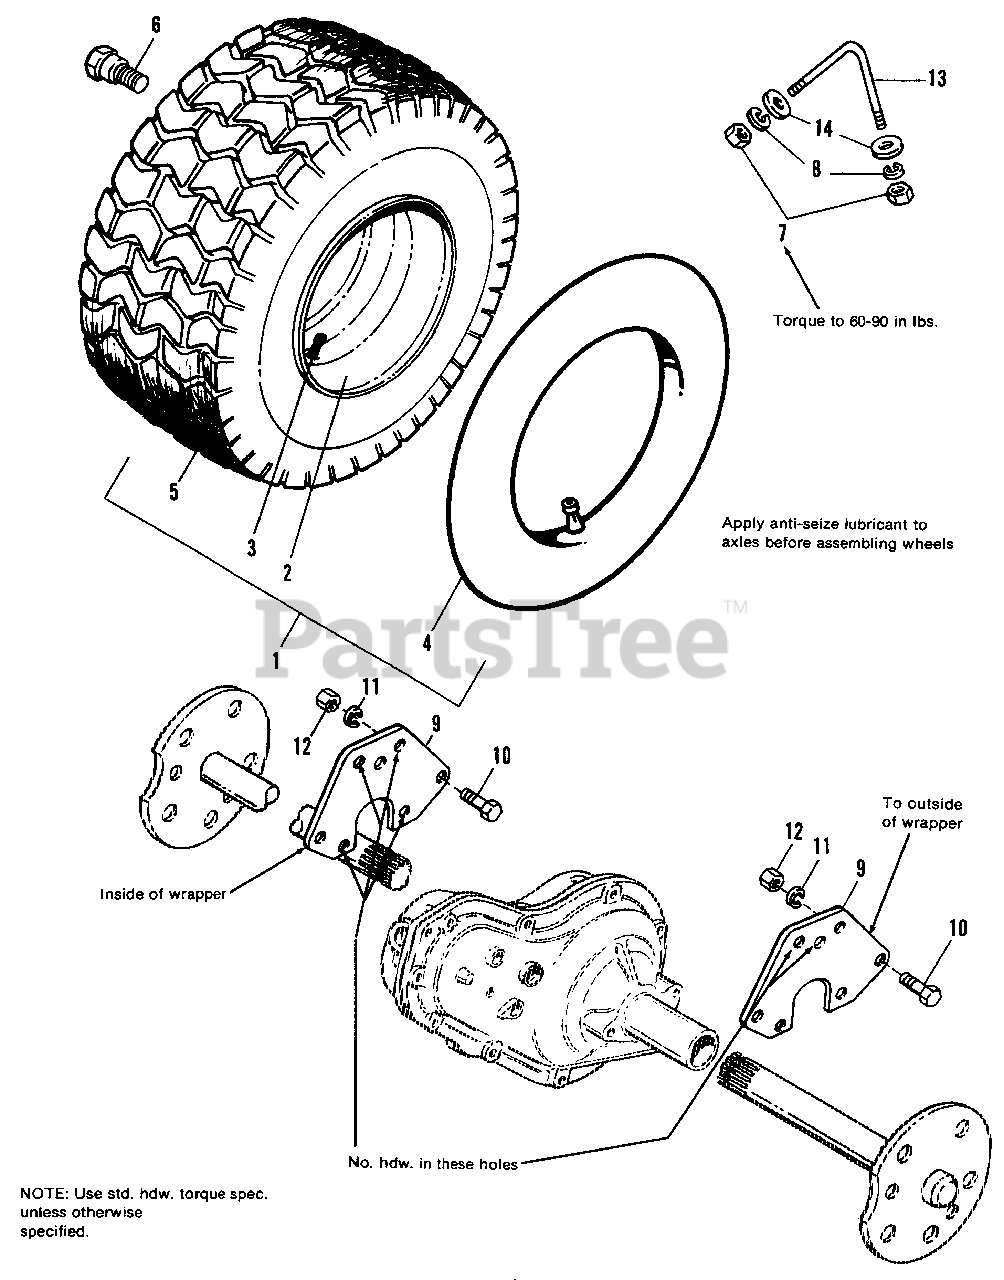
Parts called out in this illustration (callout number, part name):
1	WHEEL & TIRE ASSY. (includes Ref. Nos. 2, 3, 4 & 5)(23 x 8.50-12)
1	WHEEL & TIRE ASSY. (includes Ref. Nos. 2, 3, 4 & 5)(23 x 10.50-12)
3	VALVESTEM
4	TUBE, 23 x 8.50-12
4	TUBE, 23 x 10.50-12
5	TIRE, Turf, 23 x 8.50-12 (Carlisle)
5	TIRE, Turf, 23 x 8.50-12 (Goodyear)
5	TIRE, Turf, 23 x 10.50-12 (Carlisle)
7	NUT, Hex 5/16-18
8	LOCKWASHER, 5/16
9	BRACKET, Support
10	SCREW, Whizlock 3/8-16 x 1
11	LOCKWASHER 3/8
12	NUT, Hex 3/8-16
13	BOLT, Axle
14	WASHER, 5/16
